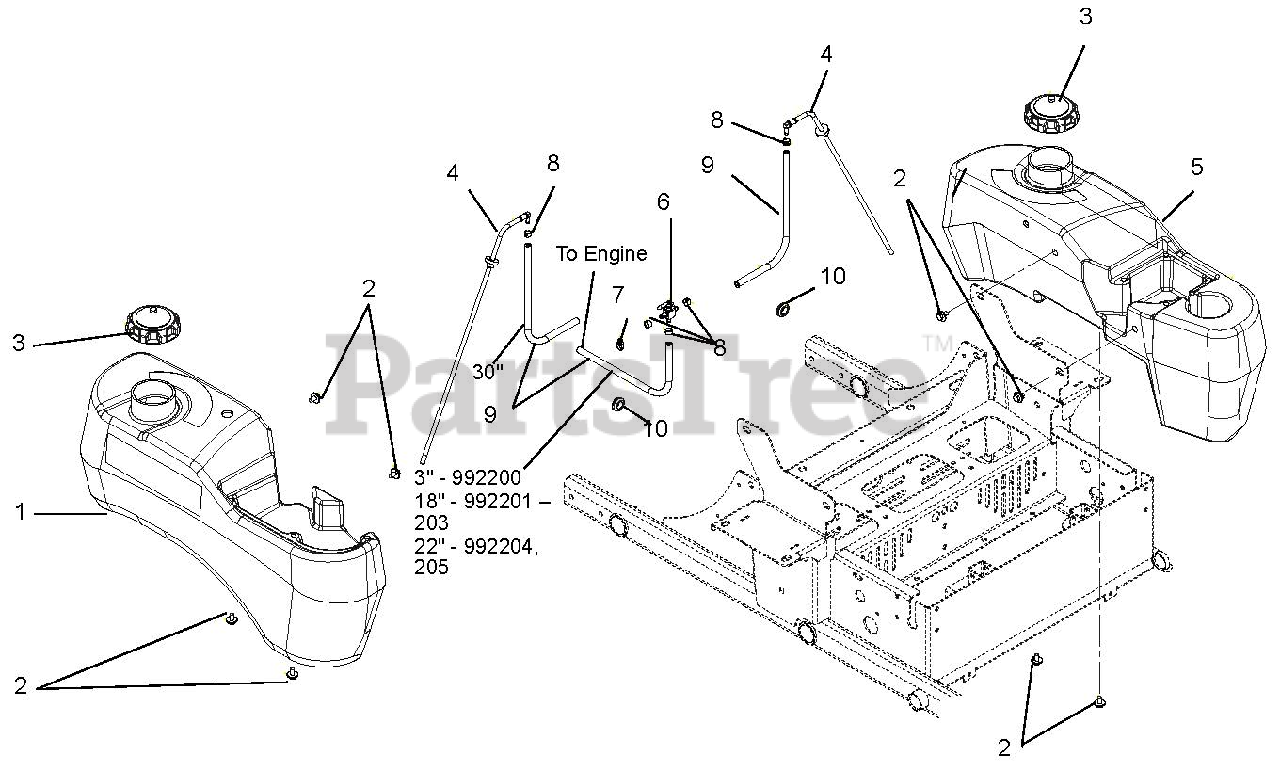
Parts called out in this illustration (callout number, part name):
1	Tank, Right Hand Fuel
2	Bolt, SEMS .31-18 x .62
3	Cap, Fuel
4	Assembly, Large Tank Fuel Pick-Up
5	Tank, Left Hand Fuel
6	Valve, Fuel
7	Routing Clip (1/2" ID)
8	Clamp, Fuel Line
9	Hose, .25 Low-Perm Bulk Gas
10	Grommet, Rubber 5/8 ID/1.13 OD
